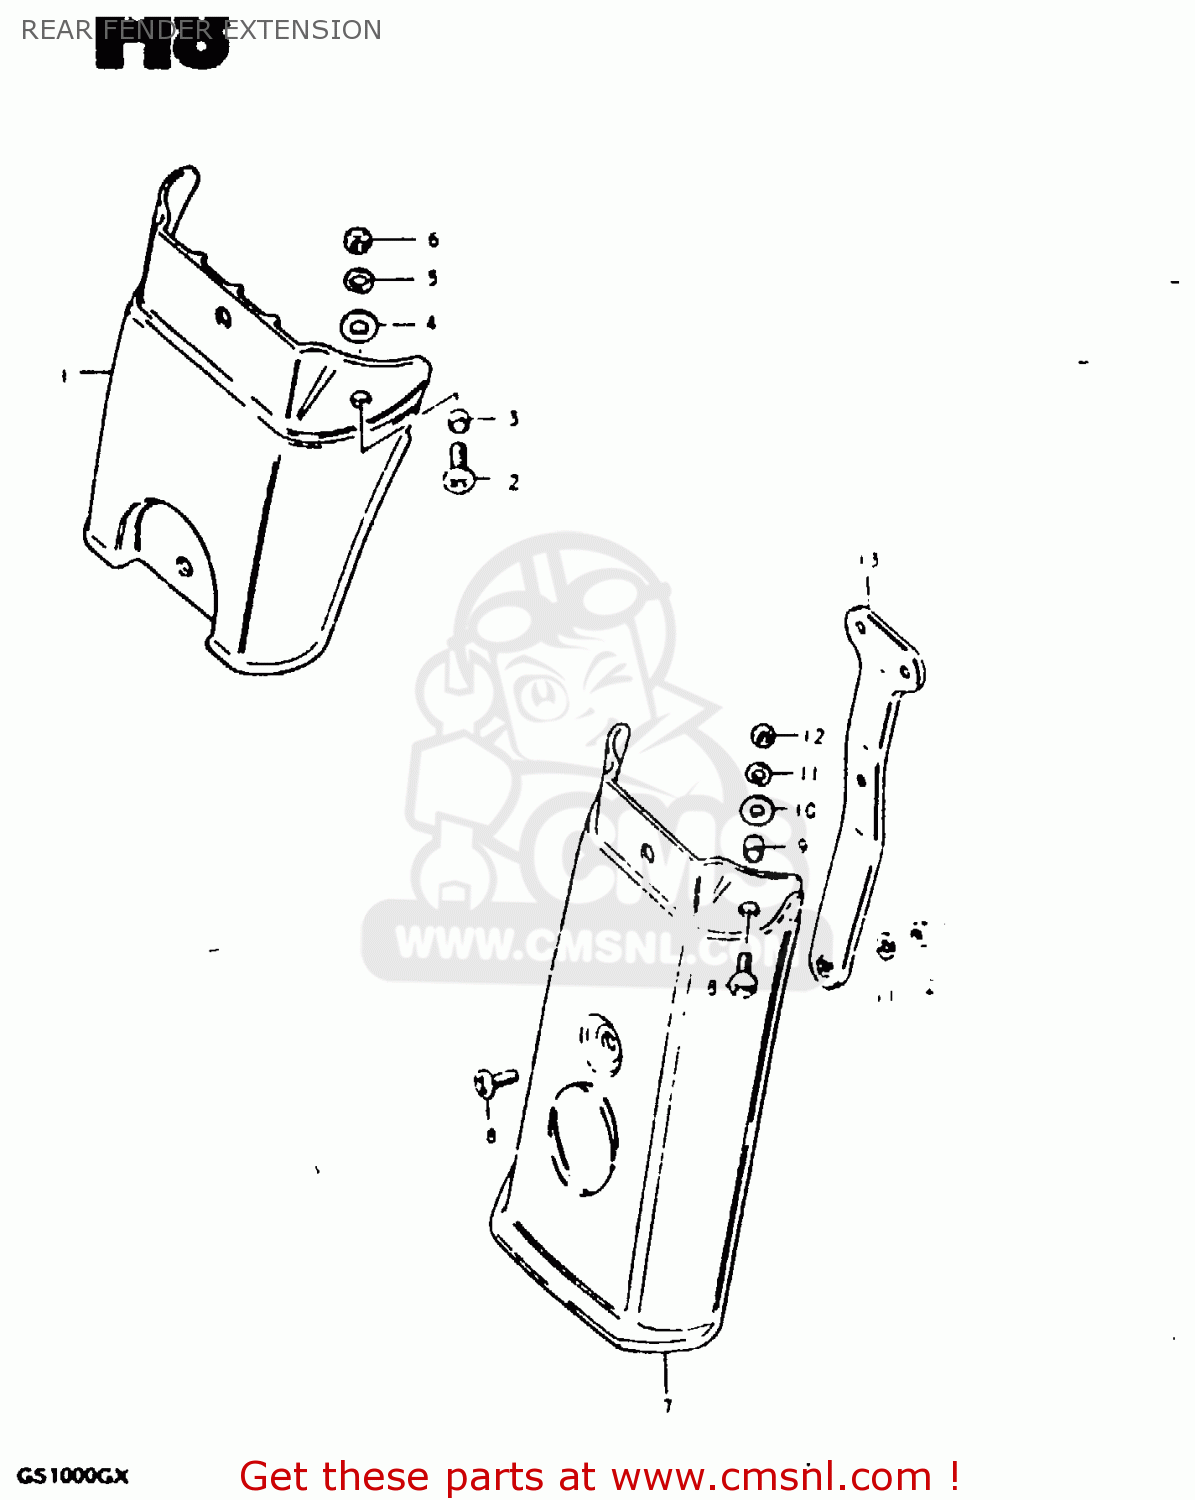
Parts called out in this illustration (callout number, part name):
1	EXTENSION,REAR FENDER
2	SCREW (6X15)
3	SPACER(6.2X8.3X5.7)
4	WASHER(6.5X18X1)
5	LOCK WASHER
6	NUT
7	EXTENSION, REAR FENDER
8	SCREW (6X15)
9	SPACER(6.2X8.3X5.7)
10	WASHER(6.5X18X1)
11	LOCK WASHER
12	NUT
13	BRACE, REAR FENDER EXTENSION
